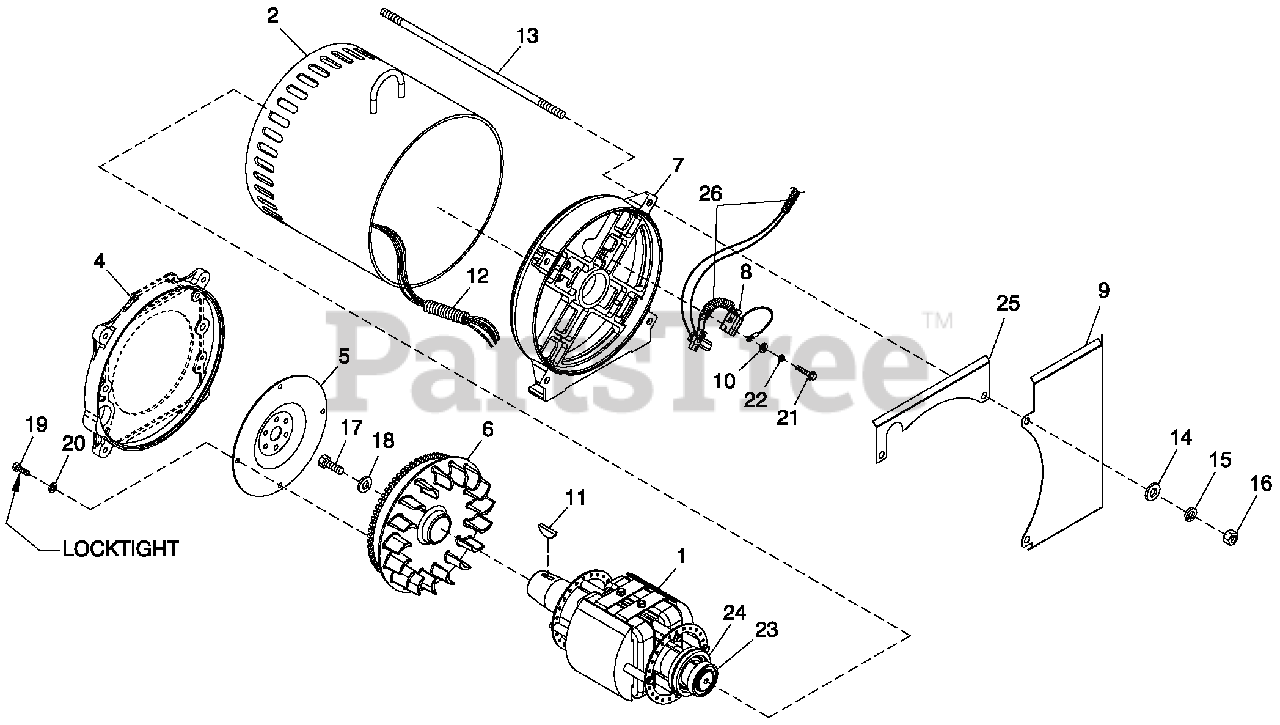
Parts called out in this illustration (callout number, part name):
1	R0T0R-2390-45KD1 CPL
2	STAT0R-390 45K 2P 1PH DIRECT
3	INSTR HYP0T TEST (N0T SH0WN)
4	ENGINE ADAPTER
5	FLEXPLATE
6	ASSY FLYWHEEL CPL W/40MM FAN B
7	REAR BEARING CARRIER 390/DRCT
8	ASSY BRUSH H0LDER 390/HSB
9	GUARD REAR BEARING CARRIER
10	WASHER FLAT #8 ZINC
11	KEY W00DRUFF #E
12	C0NDUIT FLEX 1.0" ID (35" LG)
13	STUD M14-2.0 570 G5ZINC
14	WASHER FLAT M14
15	WASHER L0CKM14
16	NUTHEXM14-2.0 G8 YEL CHR
17	SCREW HHCM16-2.0X 45 G8.8
18	SPACER .69 X 2.75 X .37 ST/ZNC
19	SCREW HHC M10-1.50 X 16 G10.9
20	WASHER L0CKM10
21	SCREW HHTT M 4-0.7X16BP
22	WASHER L0CK#8-M4
23	BALL BEARING-45 MM
24	SLIP RING MACHINED
25	GUARD REAR BEARING CARRIER
26	C0NDUIT FLEX .38" ID (60" )
